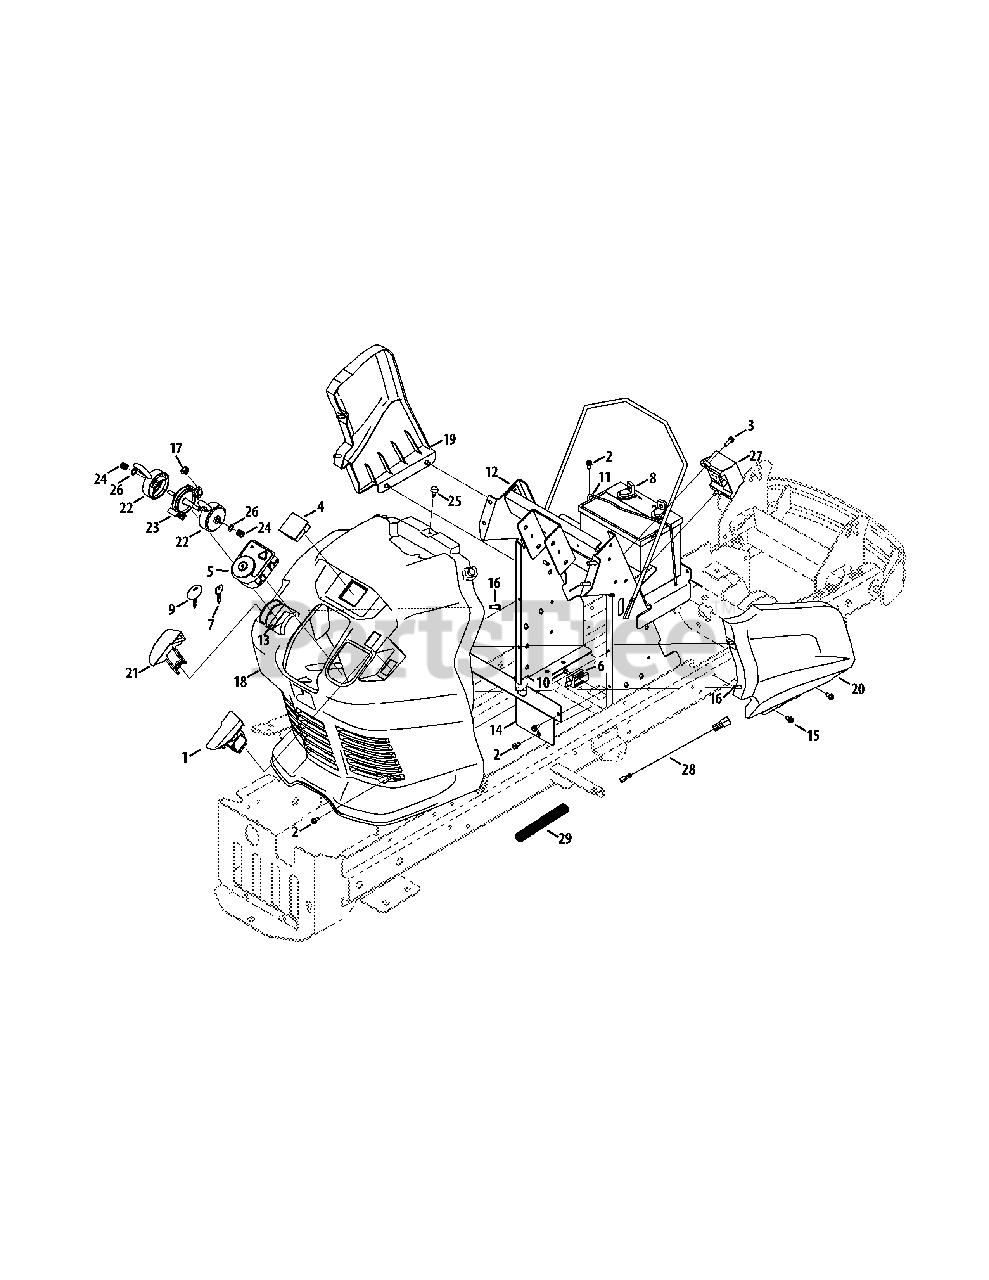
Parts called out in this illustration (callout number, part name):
1	PTO Switch Assembly
2	Hex Washer Screw, 1/4-20 x .500
3	Hex Washer Screw, 1/4-20 x .750
4	Hour/Service Minder Indicator Meter
5	Key Switch
6	Interlock Switch
7	Universal Key - Black
9	Universal Key - Yellow
10	Shoulder Screw, #10-32 x .500
11	Battery Strap
12	Steering/Battery/Dash Frame Assy.
13	Throttle Control Mount Bracket
14	Engine Air Upper Shield
15	Hex Washer Screw, 5/16-18 x .750
16	Hex Washer Screw, 5/16-14 x 1.00
17	Hex Washer Screw, #10-16 x .375
18	Dash
19	LH Dash Panel
20	RH Dash Panel
21	Cruise/Brake Lever
22	Choke/Throttle Control
23	Choke/Throttle Index Disc
24	Compression Spring, .50 x .50
25	Bumper, .62 x .3
26	Flat Washer, .344 x .620 x .033
27	Wire Harness (GT2000 & GTX2100)
27	Wire Harness (GTX2154LE)
28	Reverse Jumper Harness
